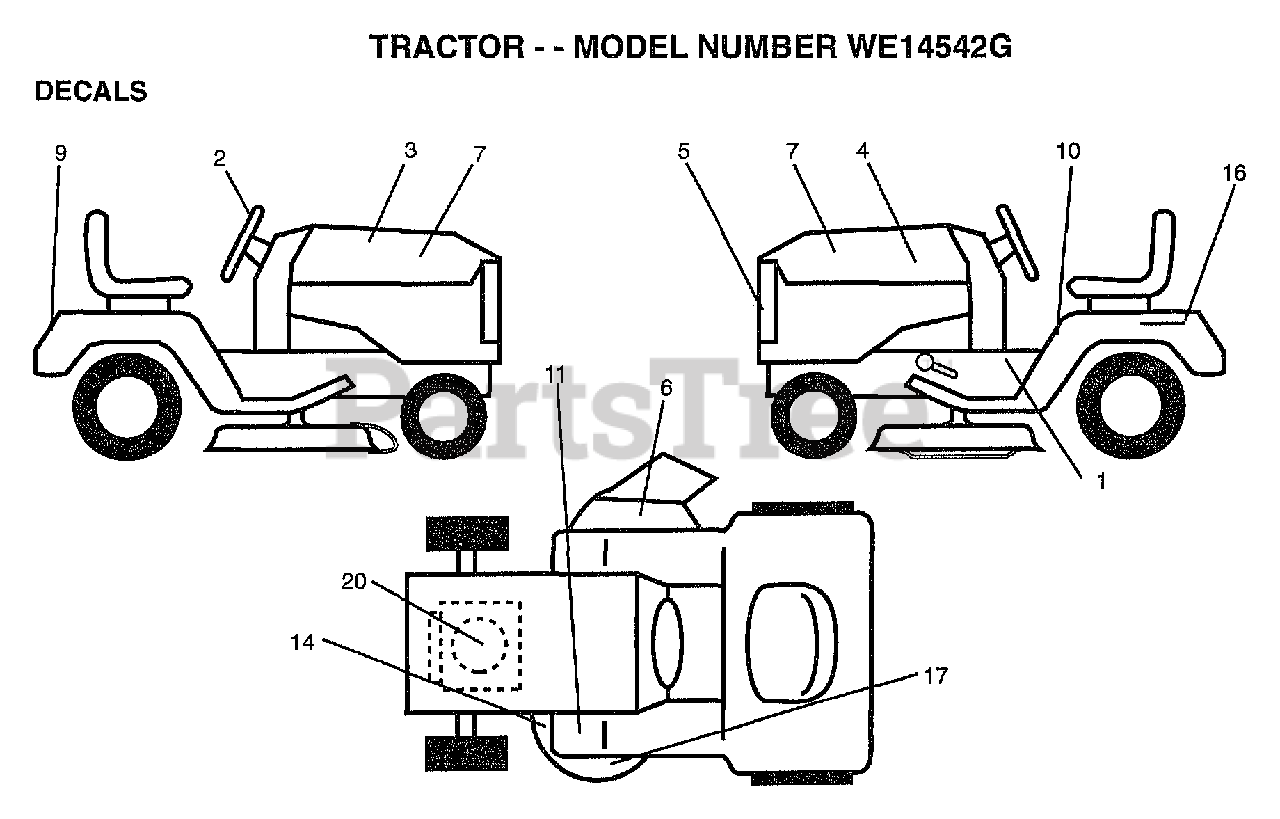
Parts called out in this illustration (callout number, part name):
1	"DECAL.OPER,SDL"
2	DECAL, INS STRG WH
3	DECAL.HOOD.RH.
4	DECAL.HOOD.LH
5	DECAL, GRILLE LENS
6	"DECAL, WARNING"
7	DECAL PANEL SIDE
9	DECAL.FENDER.LOGO
10	DECAL.CAUT.ENG/FR
11	DECAL T
14	"DECAL-SCHEM,BELT"
16	DECAL.BATRY.3-3908
17	DECAL, DECK GRASSEATER
20	DECAL, ENGINE
